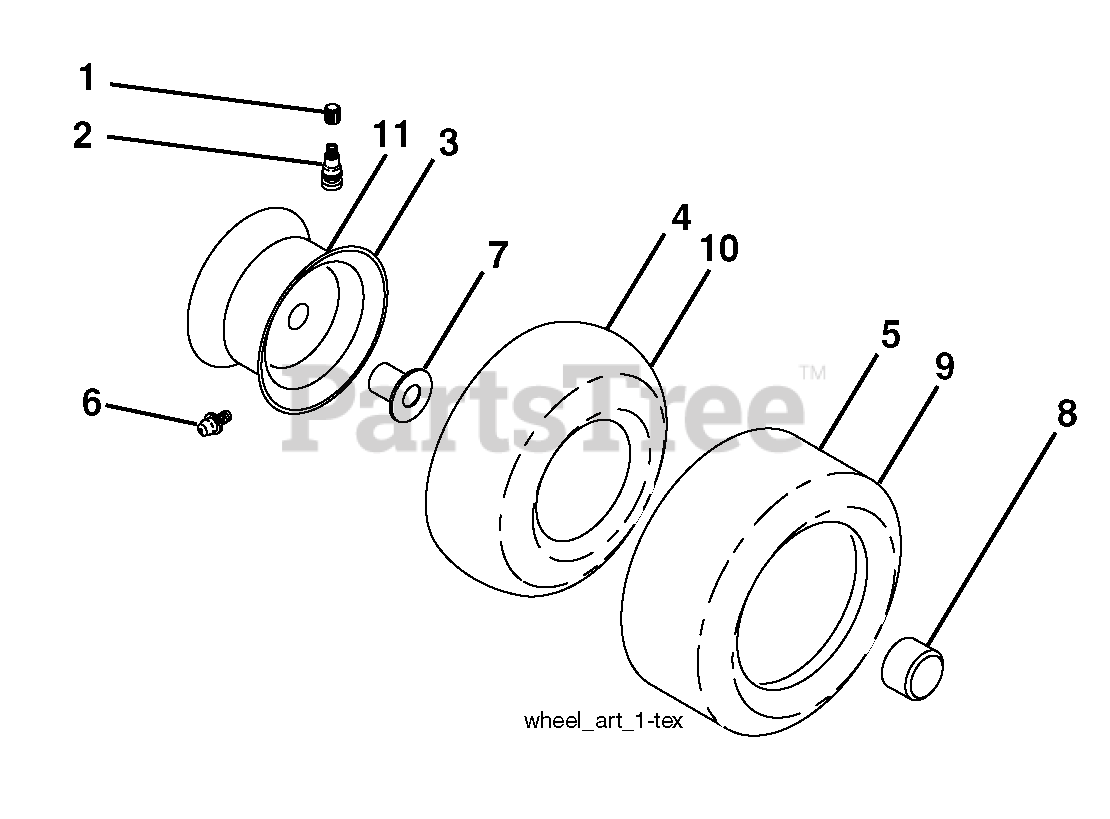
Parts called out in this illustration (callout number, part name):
1	Cap Valve Tire
2	Stem Valve
3	Rim Front
4	Tube Front
5	Tire Front 15 x 6.0-6
6	Fitting Grease
7	Bearing Flange
8	Cap Axle Blk 1 50 x 1 00
9	Tire R 18 x 9.5-8 Turf Saver LT
10	Tube Rear
11	Rim Asm 8" Rear
